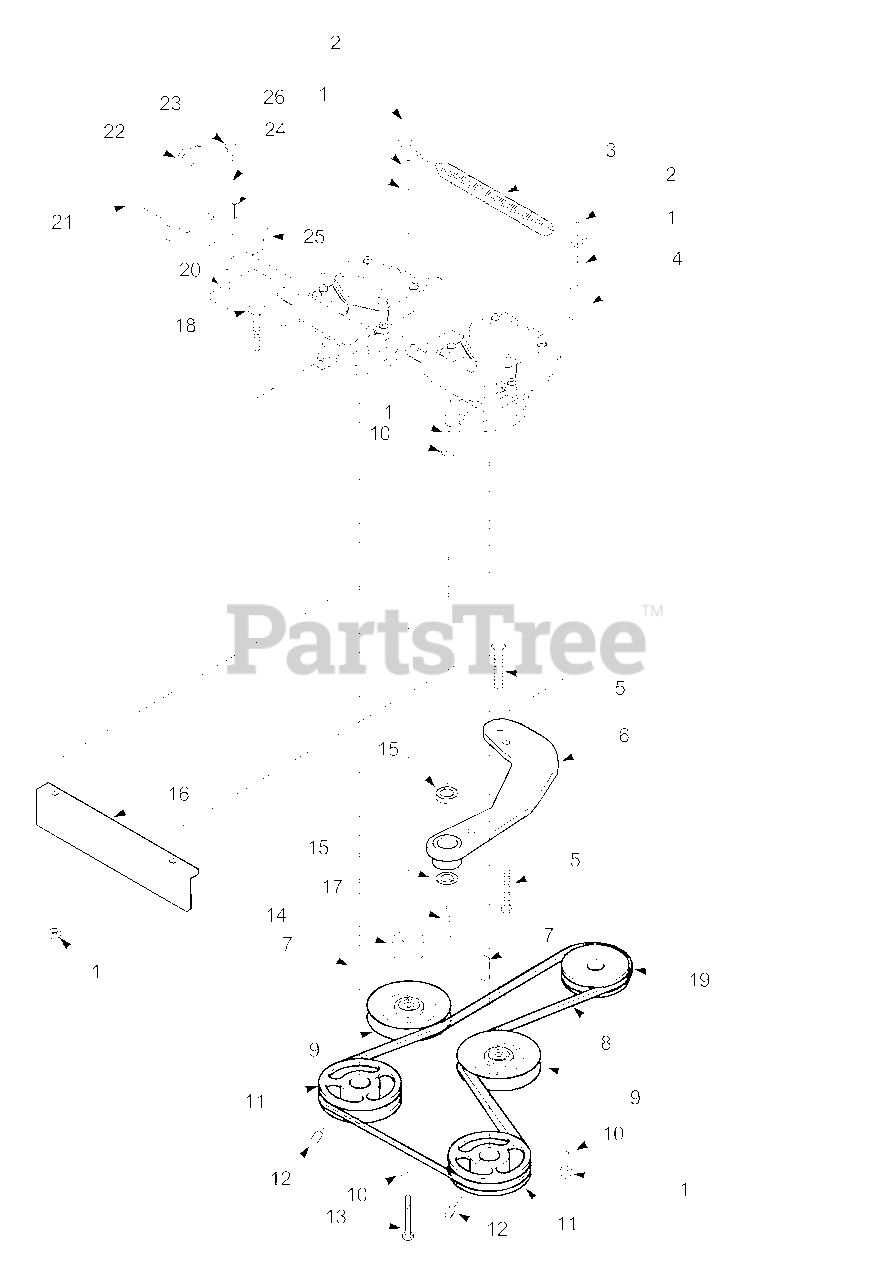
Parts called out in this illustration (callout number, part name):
1	Nut, Elastic Stop 3/8-16
2	Nut, Center Lock 3/8-16
3	Spring
4	Spacer
5	Bolt, Hex Head 3/8-16 x 2-1/4" Grade 8
6	Idler Arm, Pump Drive
7	Key, 5 x 5 x 25mm
8	Belt, Transmission
9	Pulley
10	Flatwasher, 3/8-.391 x .938 x .105
11	Pulley, 4.45 Dia.
12	Set Screw, 5/16-18 x .375
13	Bolt, 3/8-16 x 3-1/4" Grade 8
14	Spacer, Idler
15	Bearing
16	Belt Guard
17	Bolt, Hex Head 3/8-16 x 2-1/2"
18	Bolt, Carr. 3/8-16 x 1-1/4"
19	Pulley, 4.45 Dia. - 1" Bore
20	Clamp Plate
21	Hex Head Capscrew, 1/4-20 x 3/4"
22	Control Lever, Pump
23	Hex Head Capscrew, 1/4-20 x 1-1/4"
24	Lockwasher, 1/4"
25	Block, Pump Control
26	Flatwasher, 3/8-.391 x .938 x .105
